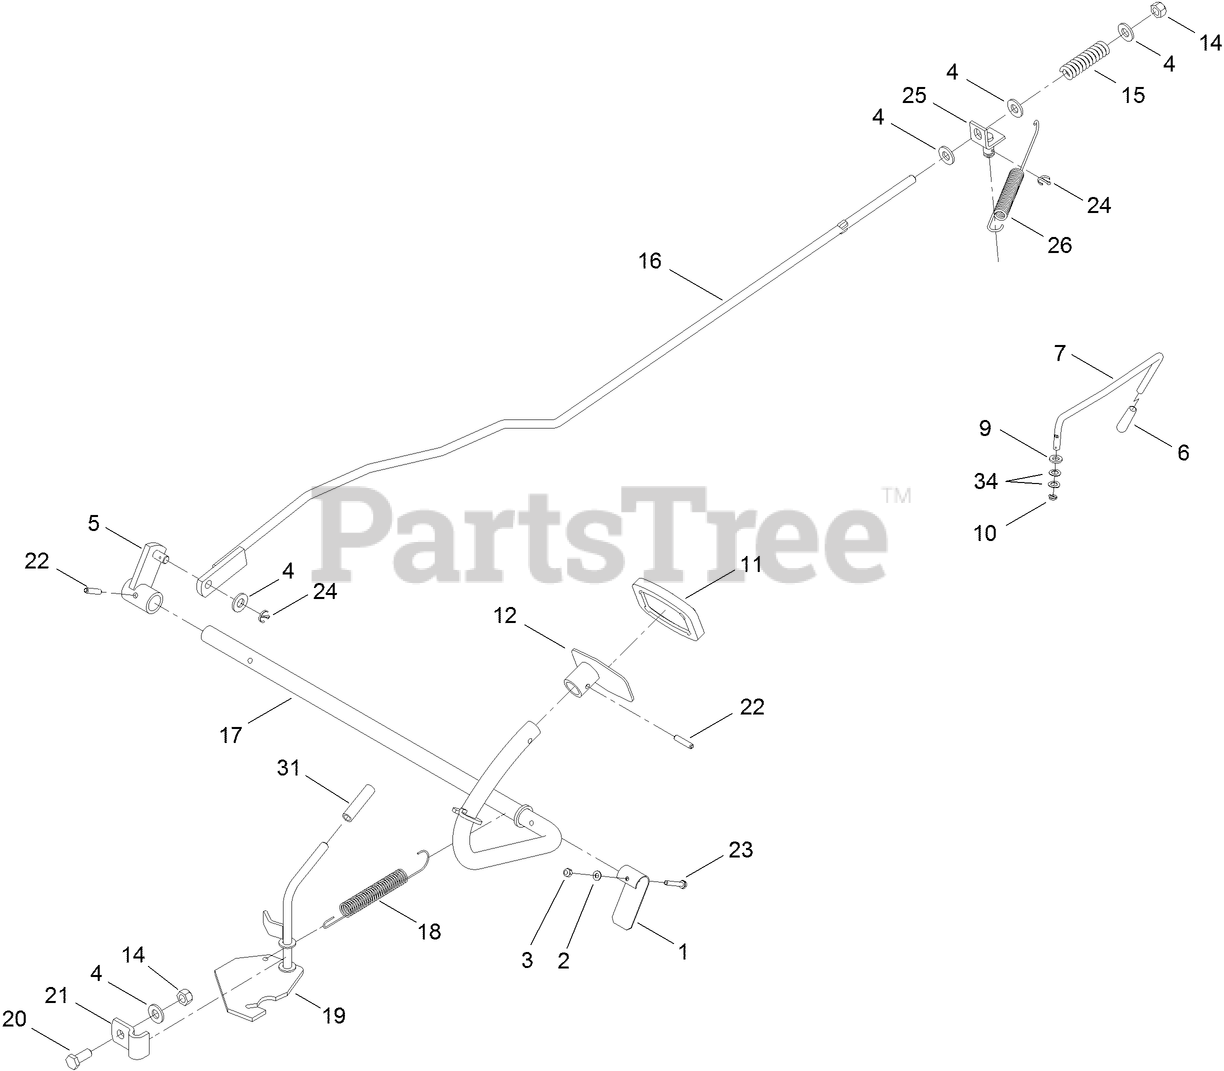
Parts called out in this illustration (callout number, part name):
1	LEVER-SPRING
2	WASHER
3	NUT-HEX
4	WASHER-PLAIN
5	BRACKET-ROD, BRAKE
6	CAP-BYPASS LEVER, HYDRO
7	ROD-LEVER, BYPASS
9	WASHER
10	PIN-COTTER
11	PAD-PEDAL
14	NUT-LOCK, NI
15	SPRING-BRAKE
16	ROD-CONNECTING, BRAKE
17	Shaft-Brake
18	SPRING-BRAKE, HAND
19	LEVER-BRAKE, HAND
20	SCREW-HH
22	PIN-SPRING
23	SCREW-HEX
24	PIN-COTTER
25	BRACKET-ROD, BRAKE
26	SPRING
34	Washer
